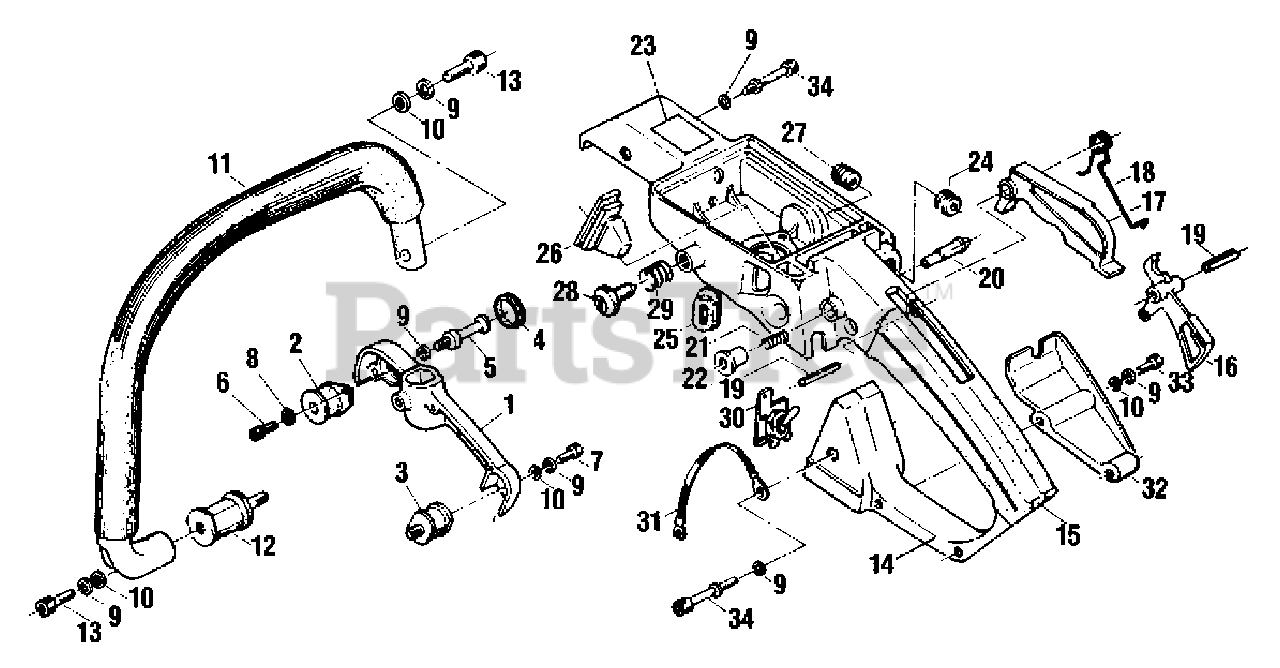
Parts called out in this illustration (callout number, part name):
1	BRACKET
2	CUSHION 22
3	CUSHION 18A
4	PLUG
5	BOLT 5
6	BOLT 4×10
7	BOLT 5×12
8	WASHER, SPRING 4 MM
9	LOCKWASHER
10	WASHER, FLAT 5.5×10×0.8
11	HANDLE, FRONT
12	CUSHION - 18
13	BOLT 5×25
14	HANDLE - REAR
15	GRIP, HANDLE
16	LEVER, THROTTLE
17	LEVER, LOCK
19	PIN, SPRING
20	STOPPER
22	KNOB, STOPPER
23	LABEL, CAUTION
25	GROMMET, CARBURETOR
26	GROMMET, ROD
27	GROMMET (B)
28	SCREW, ADJUSTER
29	SPRING
30	IGNITION SWITCH ASSY
31	LEAD - GROUND
32	REAR GUARD
33	BOLT M5×18
34	BOLT
